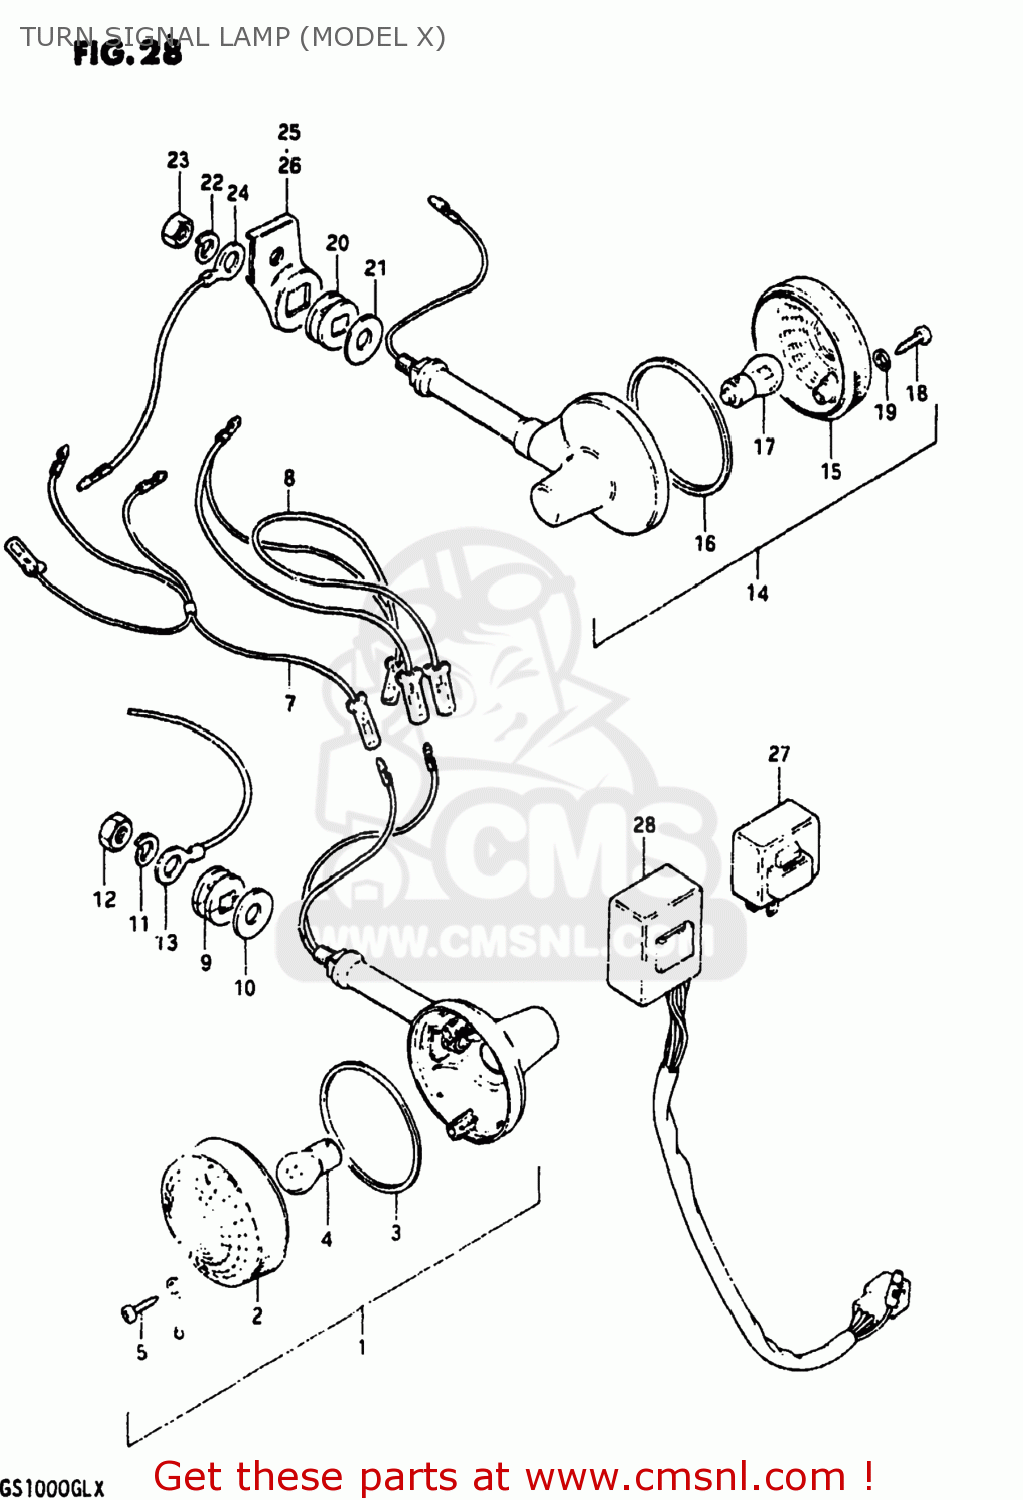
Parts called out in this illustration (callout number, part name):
1	LAMP ASSEMBLY,FRONT TURN SIGNAL
2	LENS
3	GASKET (NAS)
4	BULB(12V23W)
5	SCREW
6	GASKET (NAS)
7	WIRE
8	WIRE
9	CUSHION
10	WASHER (10.5X30X2.3)
11	LOCK WASHER
12	NUT
13	WIRE
14	LAMP ASSEMBLY,REAR TURN SIGNAL
15	LENS
16	GASKET (NAS)
17	BULB(12V23W,STANLEY,A4577A)
18	SCREW
19	GASKET (NAS)
20	CUSHION
21	WASHER (10.5X30X2.3)
22	LOCK WASHER
23	NUT
24	WIRE
25	BRACKET,REAR TURN SIGNAL
26	BRACKET,REAR TURN SIGNAL
27	RELAY ASSY,TURNSIGNAL
28	UNIT,TURN SIGNAL CONTROL
